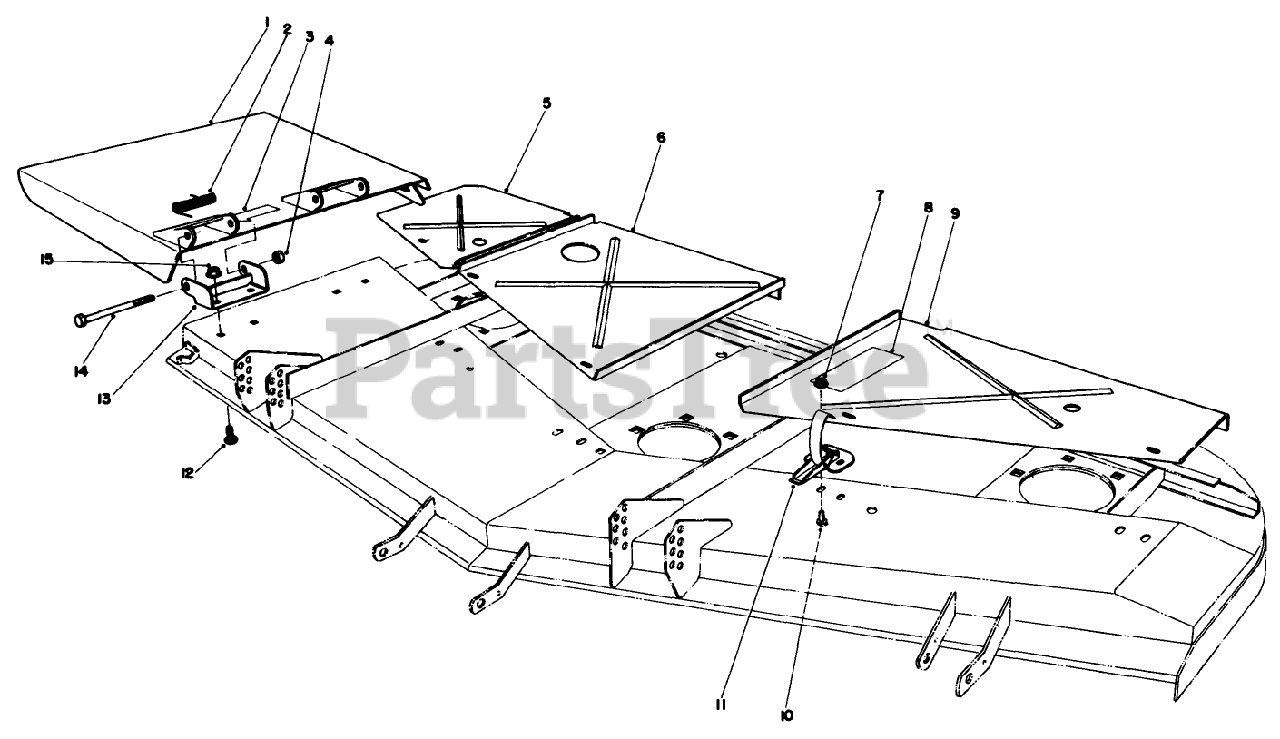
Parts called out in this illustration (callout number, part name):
1	Deflector
2	SPRING
3	DECAL - BLADE LINE
4	NUT-HEX
5	Cover-Deck R.H.
6	CTR DECK COVER R
7	NUT-LOCK, FLANGE
8	DECAL
9	Cover-Deck L.H.
10	SCREW-HWH
11	CLAMP-SLOTTED
12	SCREW-CARR
13	Bracket-Hinge
14	SCREW-HH
15	NUT-HHF, WHIZ
